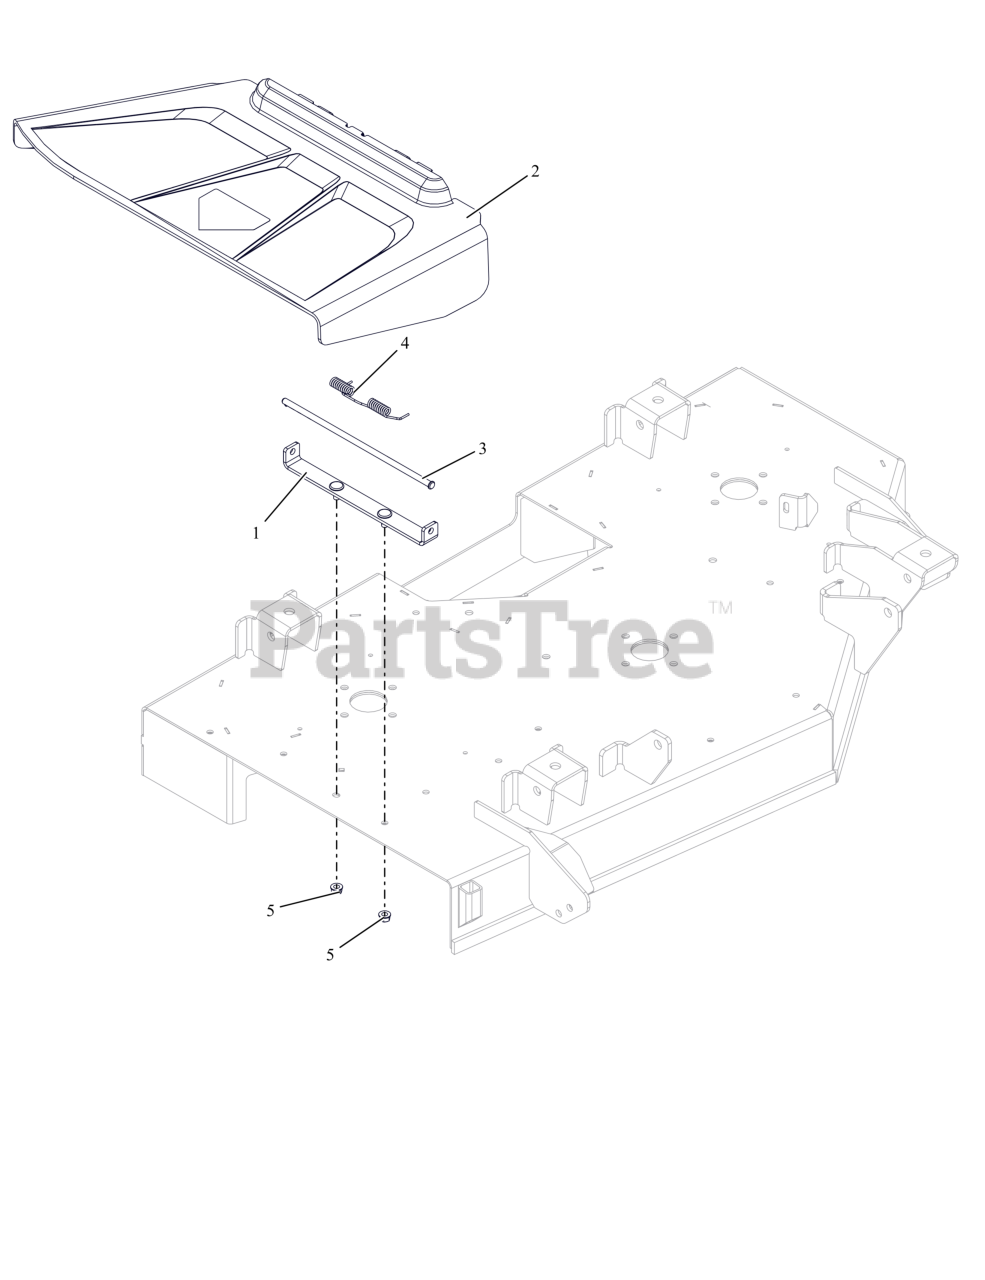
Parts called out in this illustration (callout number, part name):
2	CHUTE, SIDE DISCHARGE
3	PIN, SLIC-.312X10.45
4	SPRING-TORSION
5	NUT-LK-TOP-FLG .312-18 GF ZCC
